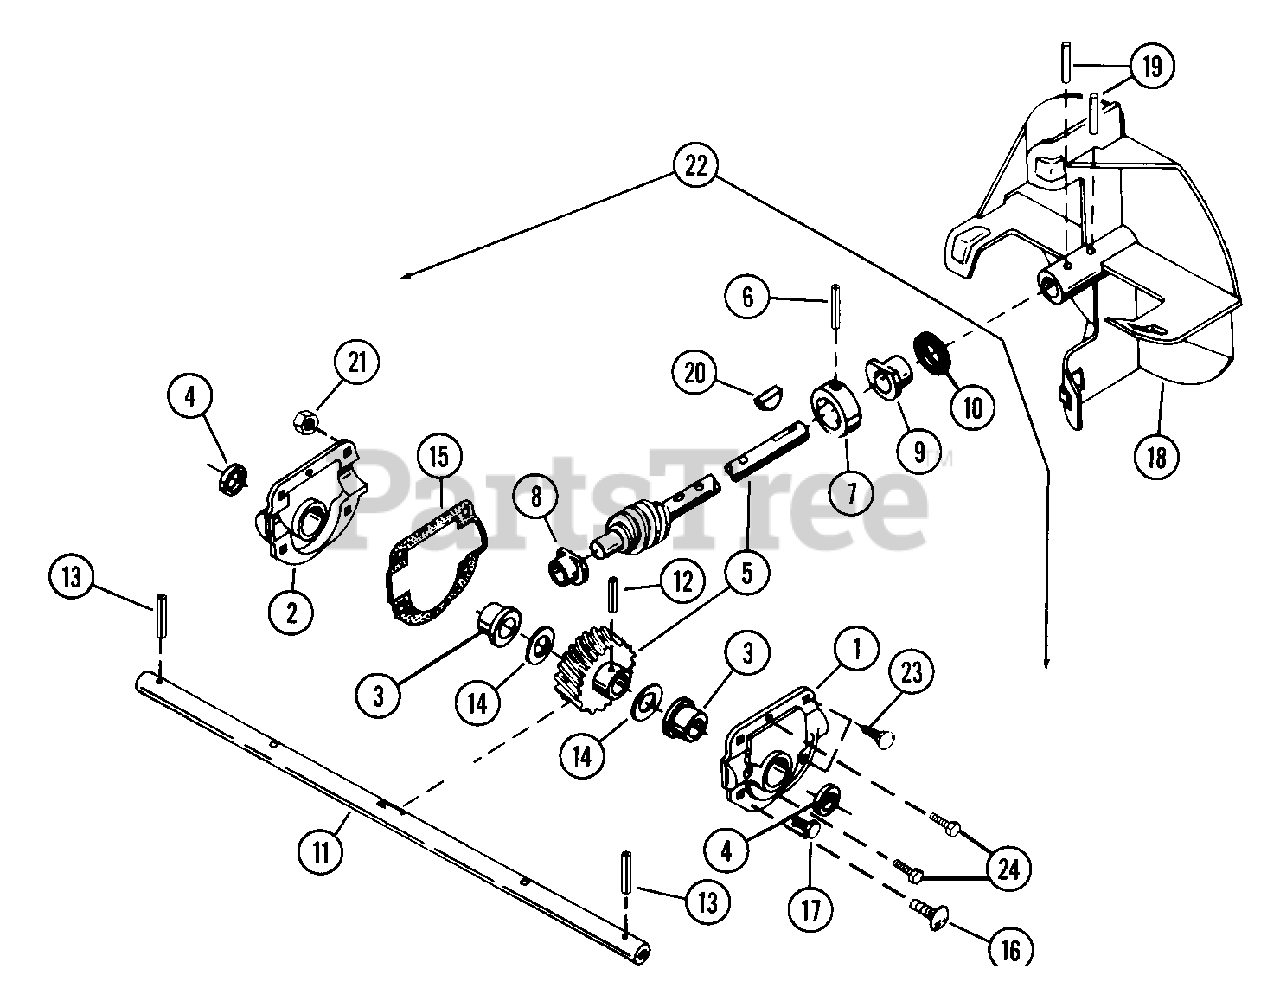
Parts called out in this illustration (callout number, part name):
1	GEAR CASE HALF L H
2	GEAR CASE HALF R H
3	BSHG-FLG1.000X1.12X.62X1.50BR
4	SEAL 1.000X1.312X.150
5	WORM SHAFT & GEAR ASSY
6	PIN-GRV .188X1.25 TP A
7	THRUST COLLAR
8	BSHG-FLG .500X.750X.750X1.000
9	BSHG-FLG .750X1.000X.750X1.250
10	O-RING .250X.943X.103
11	SHAFT, RAKE - 24"
12	PIN-GRV .313X1.44 TP C
13	PIN-ROLL .188X1.50
14	WSHR-HRD-THRS 1.007X1.542X.062
16	BLT-RDHDSQNK .25-20X.88 PL
17	BLT-SCRHFWH .38-16X.50 PL
18	FAN - 12"
19	PIN-ROLL .250X1.75
20	KEY-WDRF .188X.875X.375 SAE11
21	NUT-LK-FLG .250-20 PL
22	GEAR CASE - 24" - ALUMINUM
23	BLT-RDHDSQNK .25-20X1.25 GR5PL
24	SCR-TAP 10-24X.75 HWH PL TR
